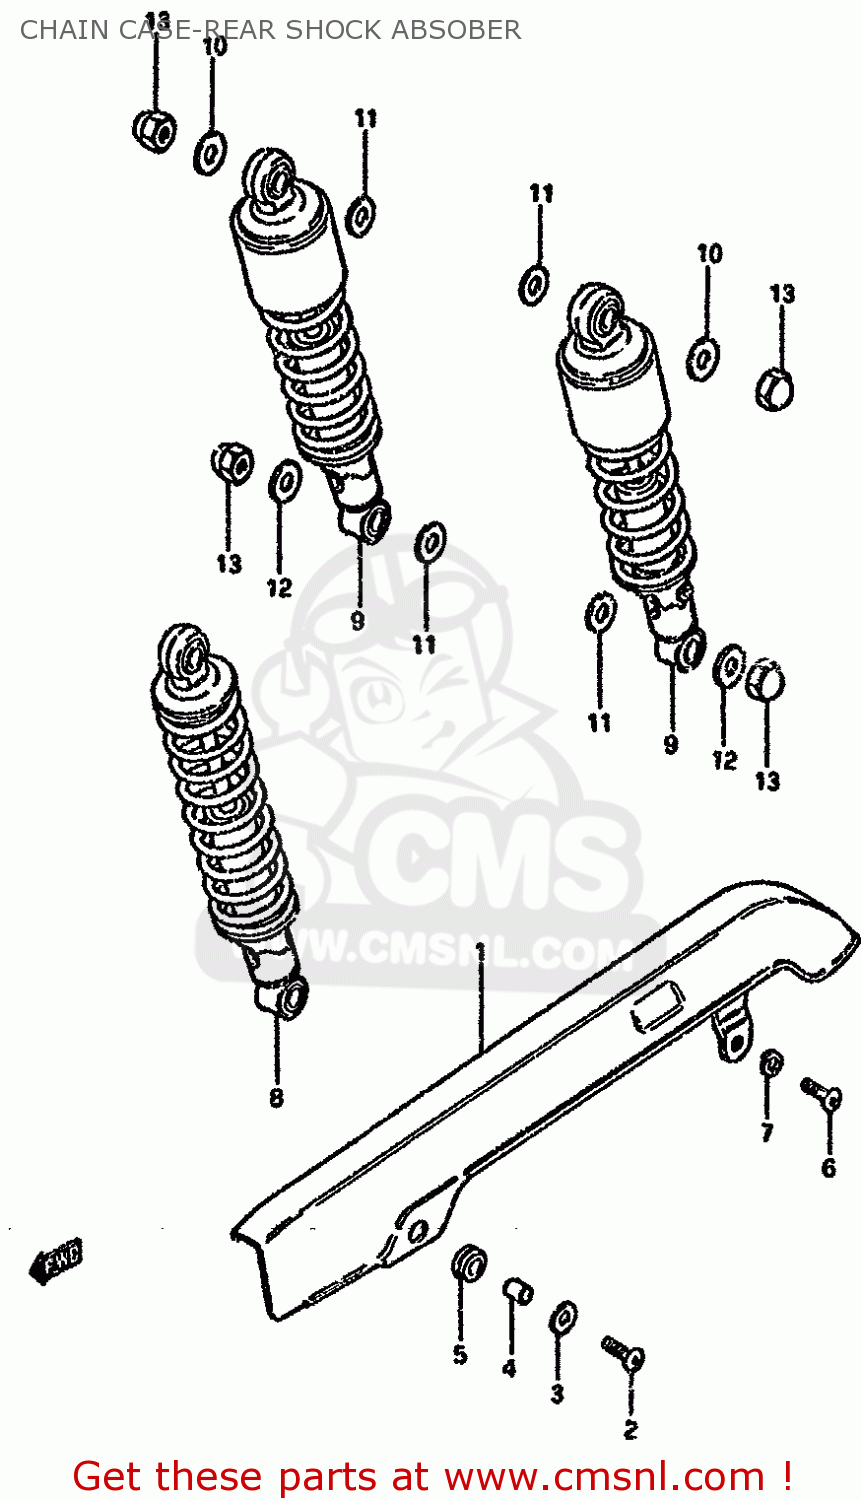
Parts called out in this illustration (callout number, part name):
1	CASE,CHAIN
2	SCREW
3	WASHER (6.5X20X1.2)
4	SPACER (7X9X7)
5	CUSHION
6	SCREW
7	WASHER,LOCK
8	ABSORBER ASSY,RR SHOCK
9	ABSORBER ASSY,RR SHOCK
10	WASHER
11	WASHER (12.5X27X1.6)
12	WASHER
13	NUT
